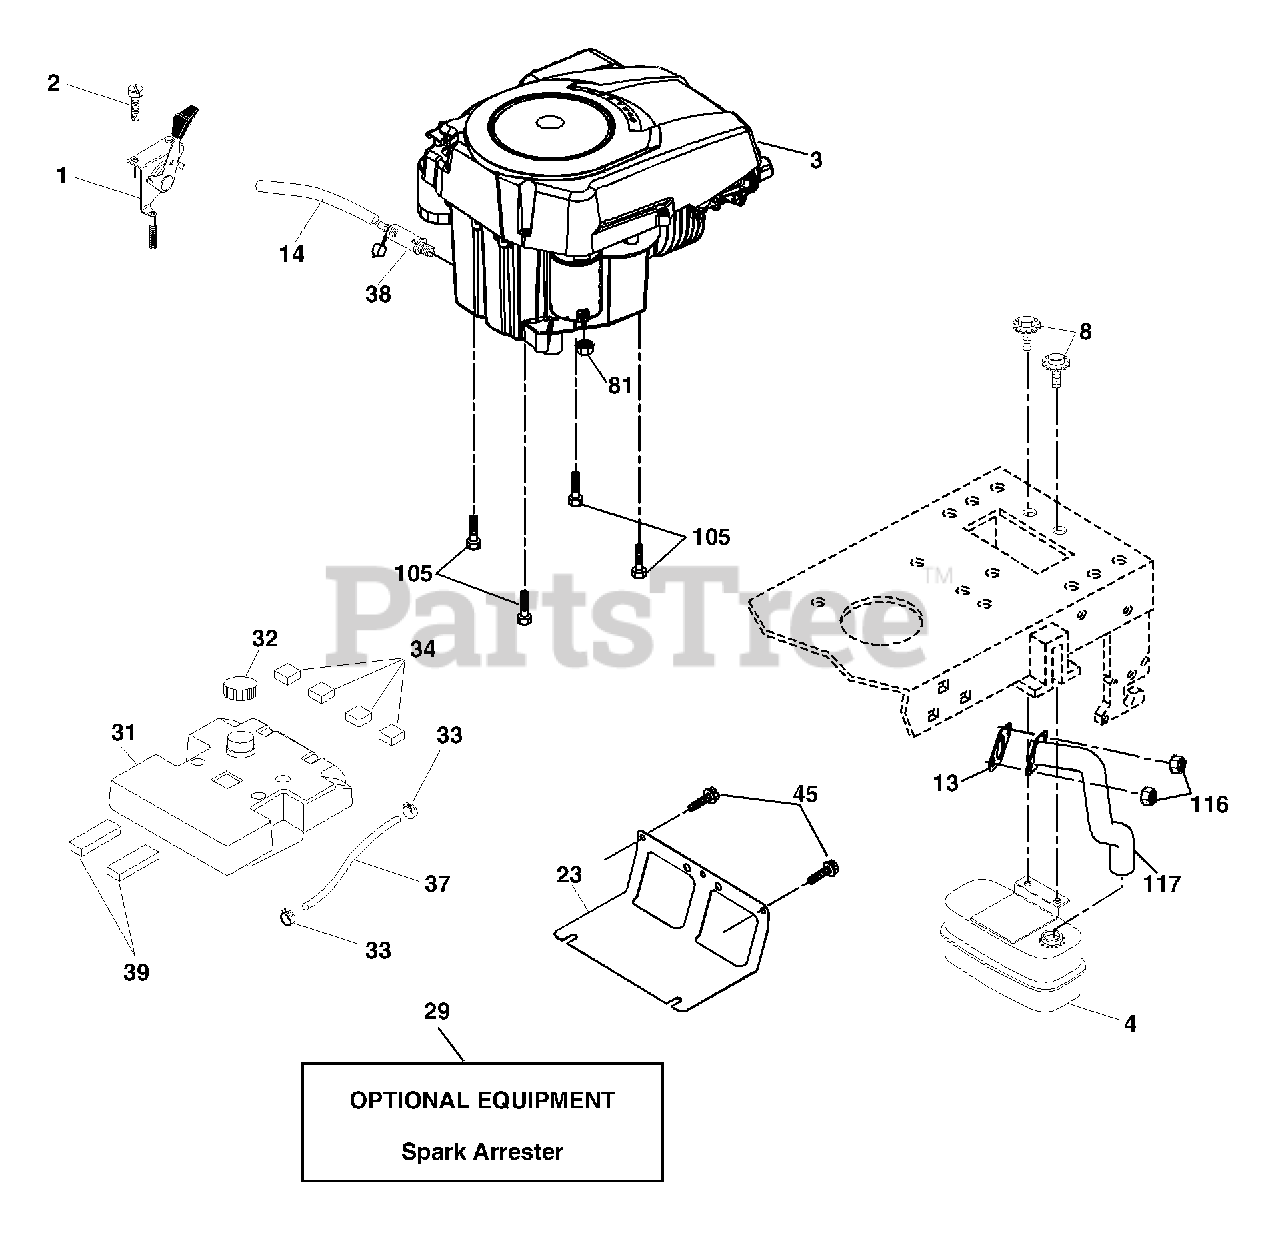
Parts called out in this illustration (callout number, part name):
1	Control Throttle/Choke Flag
2	Screw Hex Thd Cut 1/4-20 x 1/2
8	Bolt 5/16-18 unc x 3/4
13	Gasket Eng
14	Tube Drain Oil Easy
23	Shield Brn/Dbr Guard
29	Kit Spark Arrestor (Flat Scrn)
32	Cap Asm Fuel
33	Clamp Hose Black
34	Pod Spacer 1 x 1 x 1
37	Line Fuel 64"
38	Plug Drain Oil Easy
39	Pod Spacer 1.75 x .75 x .06
45	Screw Hex wsh Thdr 3/8-16 x 3/4
81	Nut Keps Hex 1/4-20
105	Screw 3/8-16 x 1
116	Nut Hex Flange Toplock M8-1.25
117	Tube Exhaust
